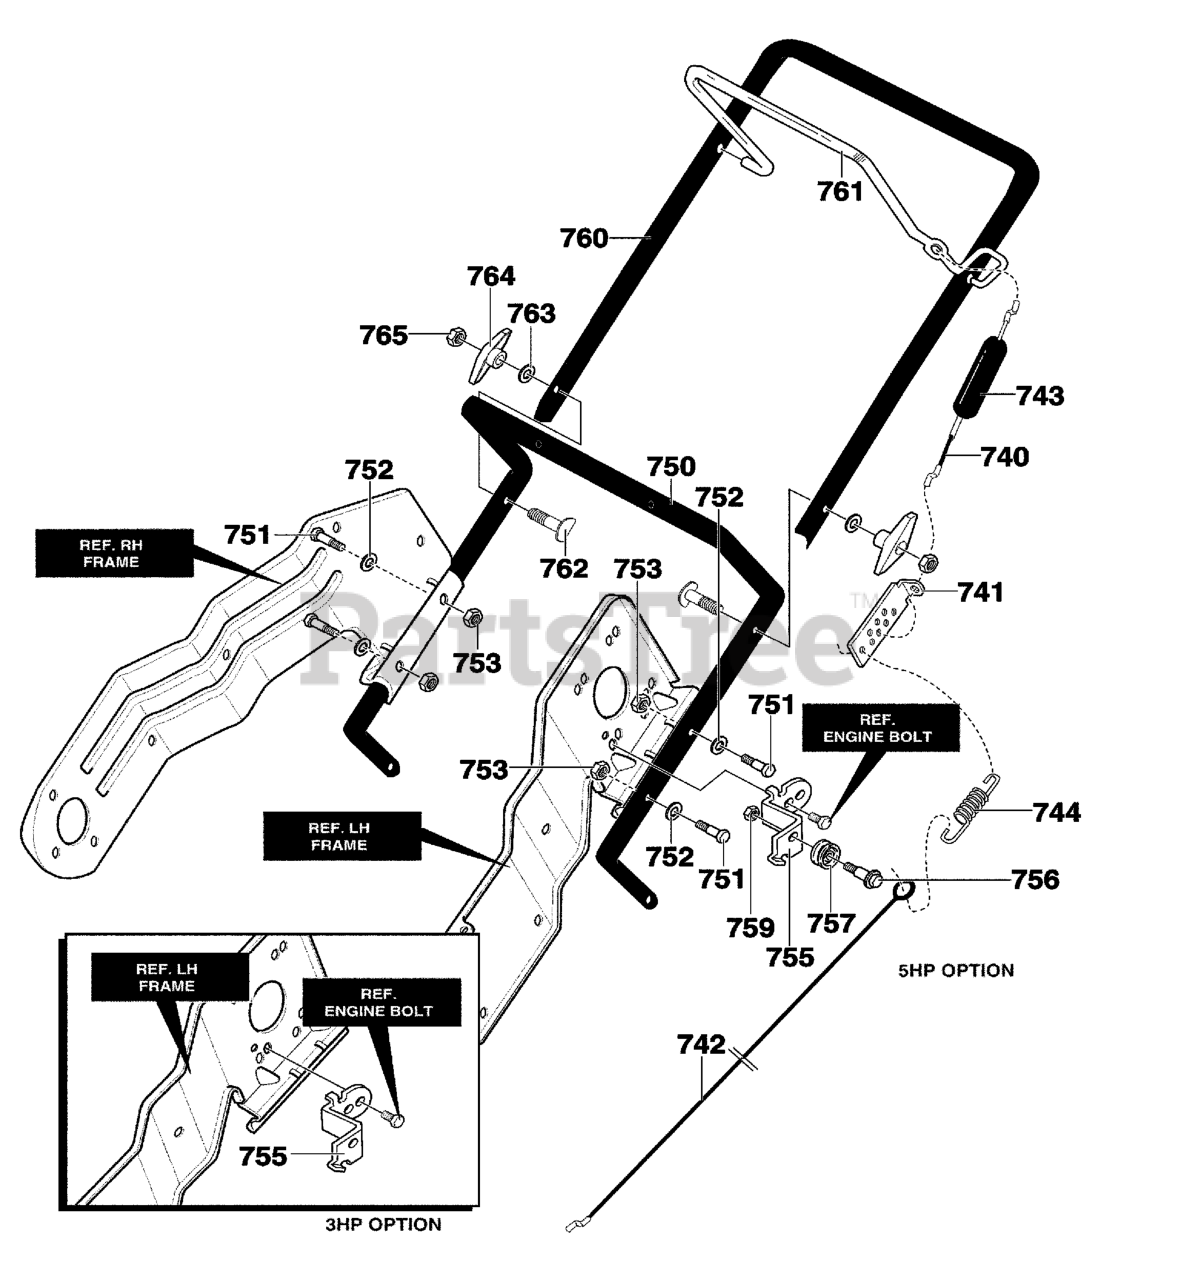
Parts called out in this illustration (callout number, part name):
740	CABLE, UPPER
741	BRACKET, CABLE ADJ
742	CABLE, LOWER CONTROL
743	BOOT, CLUTCH SPRING
744	SPRING, EXTENSION
750	HANDLE, LOWER
751	SCREW, 1/4-20X1.25
752	WASHER, FLAT
753	NUT, 1/4-20
755	BRACKET, CABLE
757	PULLEY
759	NUT, 1/4-20
760	UPPER HANDLE
761	BAIL, CONTROL
763	WASHER, FORM
764	KNOB, T 3.00 WD
765	NUT, 5/16-18
